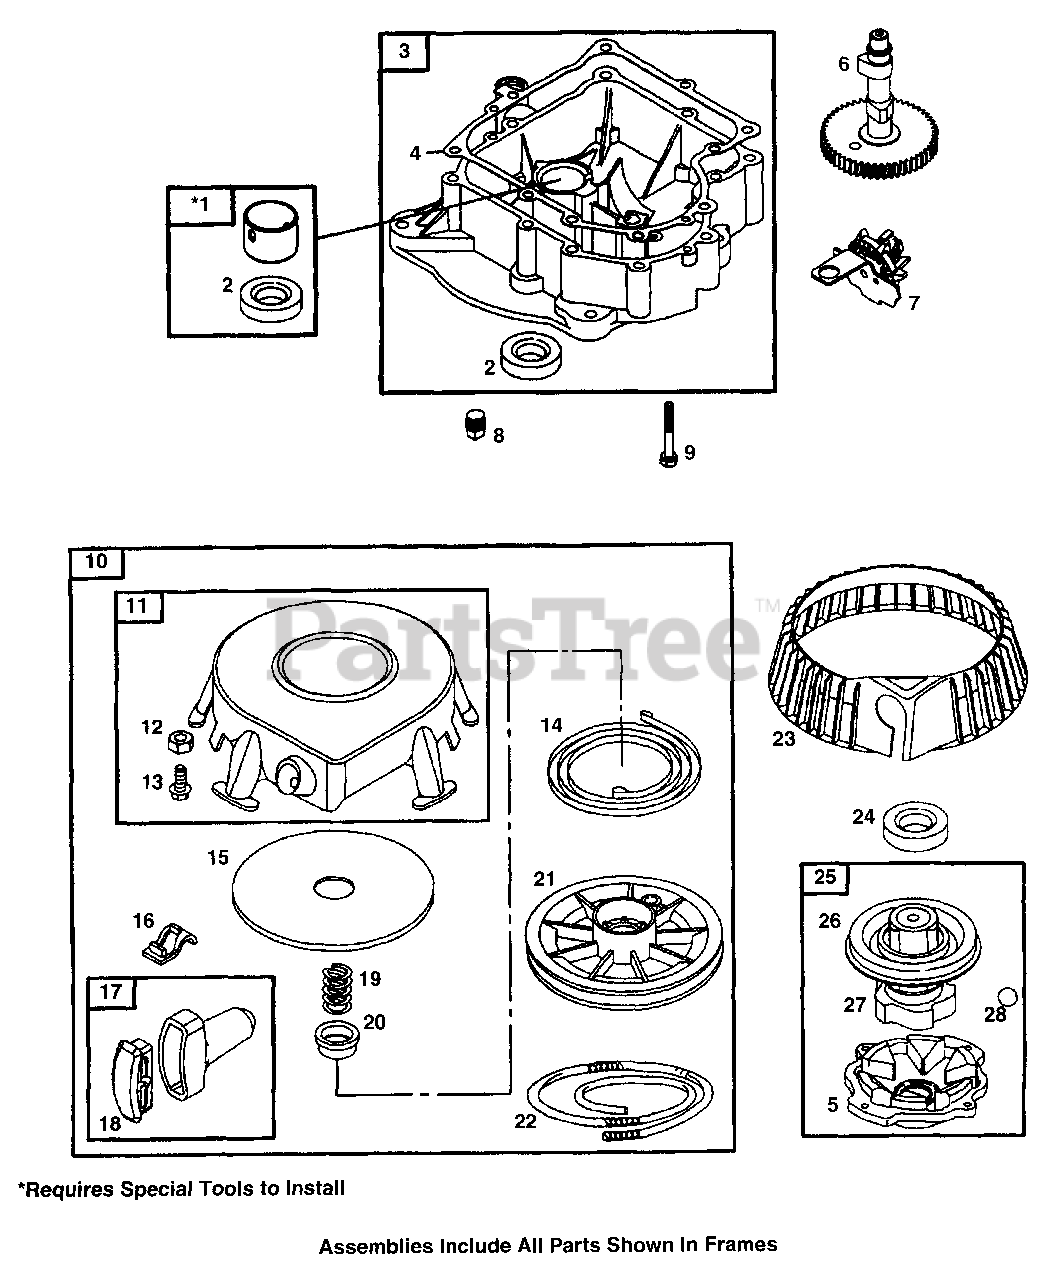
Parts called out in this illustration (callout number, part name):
1	Bushing/Seal Kit
2	Crankcase Cover Oil Seal
3	Engine Sump
4	Crankcase Gasket, .009
5	Starter Clutch Housing
7	Oil Slinger
8	Pipe Plug, Square Head
10	Rewind Starter
11	Rewind Starter Housing
12	Hex Nut
13	Screw
14	Rewind Starter Spring
15	Rewind Spacer
16	Spring Insert
17	Starter Rope Handle
18	Starter Rope Insert
19	Ratchet Spring
20	Spring Adapter
21	Starter Pulley w/ Rope
22	Starter Rope Cut to Length
23	Rewind Starter Guard
24	Ratchet Seal
25	Starter Clutch
26	Seal/Retainer Assembly
27	Ratchet Assembly
28	Clutch Ball
